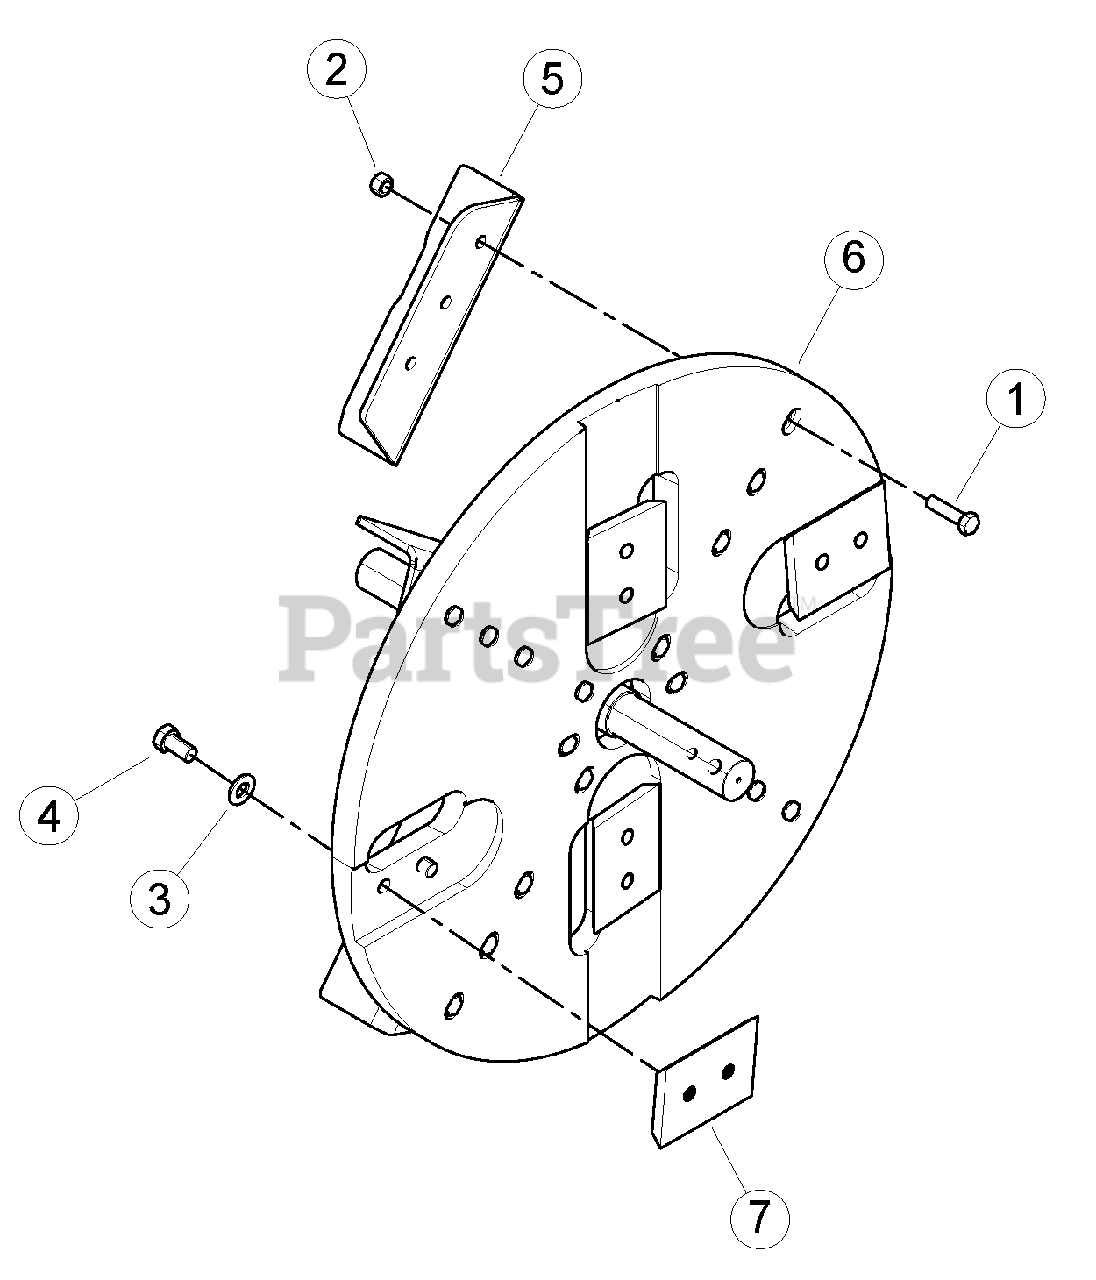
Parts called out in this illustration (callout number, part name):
1	BOLT, 1/2 X 2 HEX HD GR5 ZP
2	NUT, 1/2 CENTERLOCK GRB ZP
3	WASHER, 5/8 SAE HARDENED
4	BOLT, M16 X 2.0 X 30 HEX HD W/ PATCH
5	KIT, BIG CHIPPER FORMED PADDLES
6	ASSEMBLY, 9 INCH CHIPPER ROTOR
7	KIT, CHIPPER BLADE
